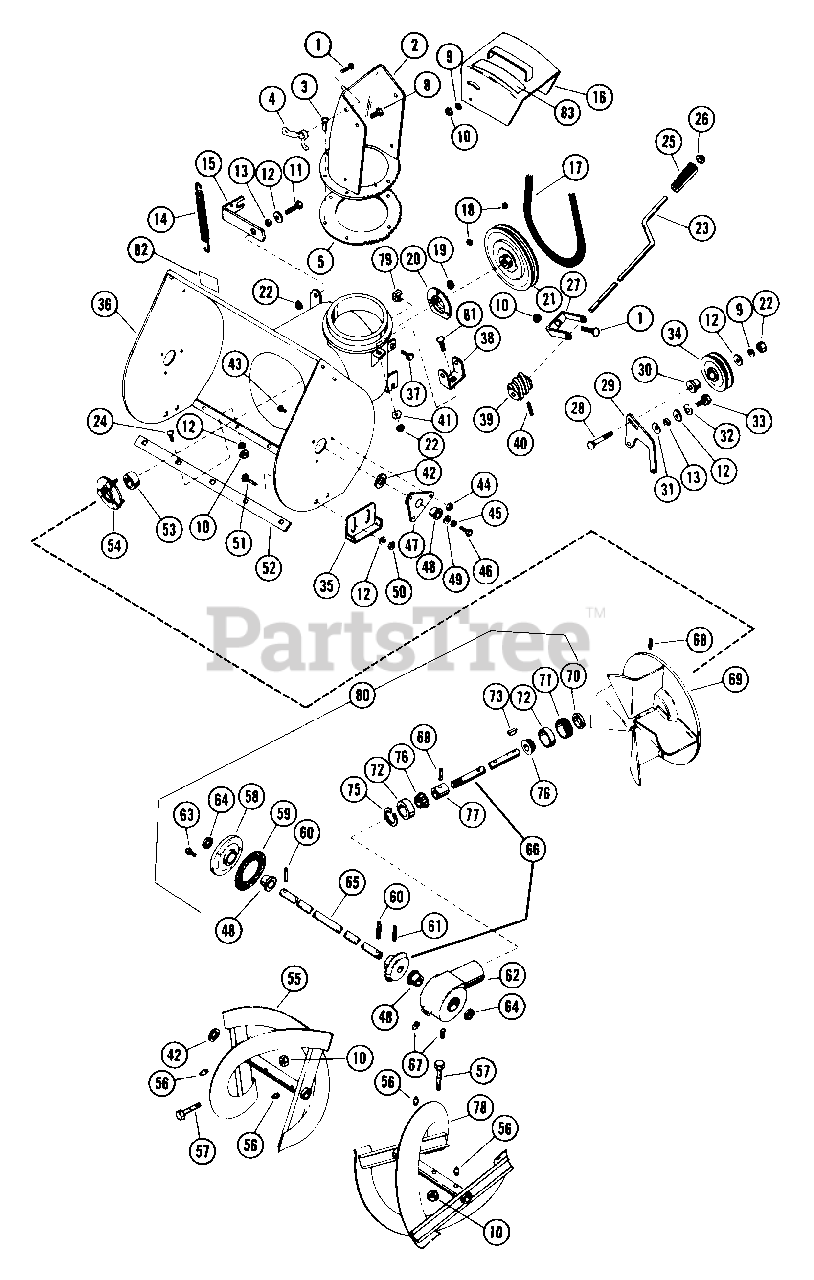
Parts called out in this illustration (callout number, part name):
1	BLT-RDHDSQSHNK .31-18X.50 YZ
2	DISCHARGE CHUTE
3	SCR-TAP 8-32X.38 SL HWH PL 23
4	WING NUT, .312-18
5	LOWER COLLAR GEAR
8	BLT-HEX .31-18X.50 PL GR2
9	WSHR-LK .312X.097 PL HVY
10	NUT-LK .312-18 GR A PL
11	BLT-HEX .31-18X.75 PL GR2
12	WSHR-FL-STL .38X.875X.083 PL
13	SPACER BUSHING .5 X .32 X .21
14	SG-TENS .125X.437X5.5 WLD 20
15	CLUTCH LEVER
16	DEFLECTOR SERVICE ASSEMBLY
17	V-BELT, 4L-WRAPPED
18	SCR-SET .32-18X.38 SKHCUPNL OH
19	NUT-LK-CTR .250-20 PL
20	BEARING FLANGE
21	PLY-? 8.0X.75
22	NUT-HEX .312-18
23	CHUTE CONTROL CRANK
24	BLT-RDHDSQNK .312-18X.62 PL
26	CAP, 3/8 ROD YWZC
27	BRACKET
28	BLT-RDHDSQNK .31-18X1.38SHT PL
29	IDLER ARM
30	SPCR, BRG .315X.50X.688X.281
31	WAVE WASHER .531X.781X.125FH
32	WSHR-LK-INT .313X.030 PL
33	BLT-HEX .31-18X.63 PL GR 2
34	IDLER
35	RUNNER
36	BLOWER HOUSING
36	BLOWER HOUSING 24 IN
37	BLT-SCRHFWH .38-16X.75 PL
38	WORM CLEVIS
39	WORM GEAR
40	PIN-ROLL .125X.75
41	WSHR-LK .313X.062
42	WSHR-FL-STL 1.010X1.505X.062PL
43	SCR-SLTR-SERNK .25-20X.62 PL
44	NUT-LK-FLG .250-20 PL
45	WSHR-LK .500X.151 HVY PL
46	BLT-HEX .50-13X1.00 PL GR2
47	BEARING SUPPORT
48	BSHG-FLG 1.000X1.12X.62X1.50BR
49	WSHR-FL-STL .511X1.441X.125 PL
50	NUT-LK-CTR .375-16 GR A PL
51	BLT-RDHDSQNK .38-16X.75 SHT PL
52	SCRAPER BLADE
53	BRG-BALL .750X1.750X.50
54	BEARING FLANGE
55	RAKE, RIGHT-20"(1ID X 13.88OD)
55	RAKE, RIGHT-24"(1ID X 13.75OD)
56	SPIN DRIVE ZERK FITTING
57	SHEAR BOLT SERVICE ASSEMBLY
58	GEAR CASE FLANGE
60	PIN-ROLL .188X1.50
61	PIN-ROLL .313X1.38
62	CASE, GEAR - C.I.
63	BLT-SERHFWH .25-20X.75 PL
64	SEAL 1.000X1.312X.150
65	FRONT GEAR SHAFT
66	SHAFT & GEAR SERVICE ASSEMBLY
67	PIPE PLUG
68	PIN-ROLL .250X1.25
70	SEAL .750X1.499X.225
71	ADJUSTMENT PLUG
72	BRG-CUP 1.781X.475
73	KEY-WDRF .188X.75X.313 SAE 9
75	RG-RTNG INT 1.781 HSG X.062
76	BRG-CONE .750X.61
77	BEARING SPACER
78	RAKE, LEFT-20"(1ID X 13.88 OD)
78	RAKE, LEFT-24"(1ID X 13.75 OD)
79	NUT-RETNR .38-16 TINRMAN
80	GEAR CASE - C.I.
80	GEAR CASE - 24" - CAST IRON
81	BLT-RDHDSQNK .31-18X.75 GR5 PL
82	ARIENS NAME PLATE
83	CAUTION LABEL
